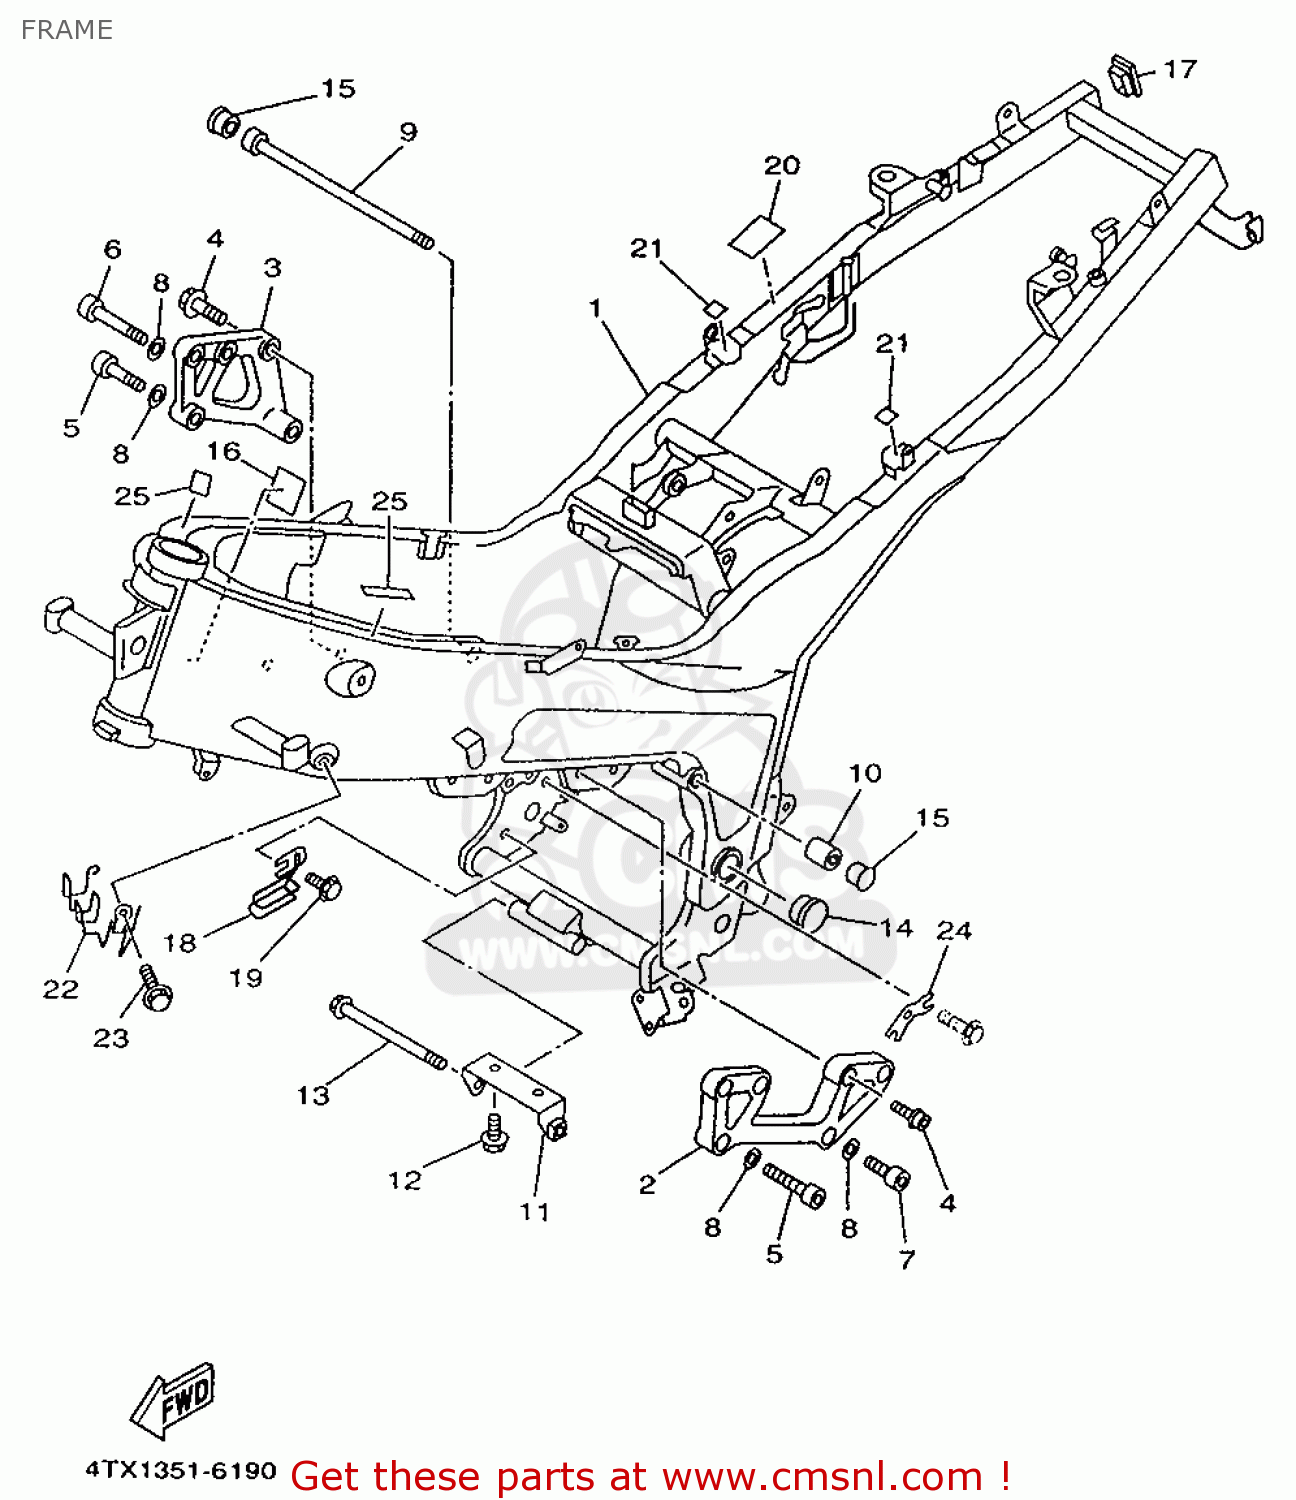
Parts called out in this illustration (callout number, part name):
01	FRAME COMP.
02	BRACKET, ENGINE 1
03	BRACKET, ENGINE 2
04	BOLT(4EB)
05	BOLT, SOCKET
06	BOLT,SOCKET
07	BOLT,SOCKET
08	WASHER (7A9)
09	BOLT, HEXAGON SOCKET HEAD(3VD)
10	NUT (11H)
11	BRACKET, ENGINE LOWER
13	BOLT, WASHER BASED(37F)
14	COVER
15	CAP
16	DAMPER
17	CAP
18	HOLDER, WIRE
19	BOLT, FLANGE
20	DAMPER
21	DAMPER 2
22	HOLDER, CABLE
23	BOLT, FLANGE
24	BRACKET 1
25	SEAL
